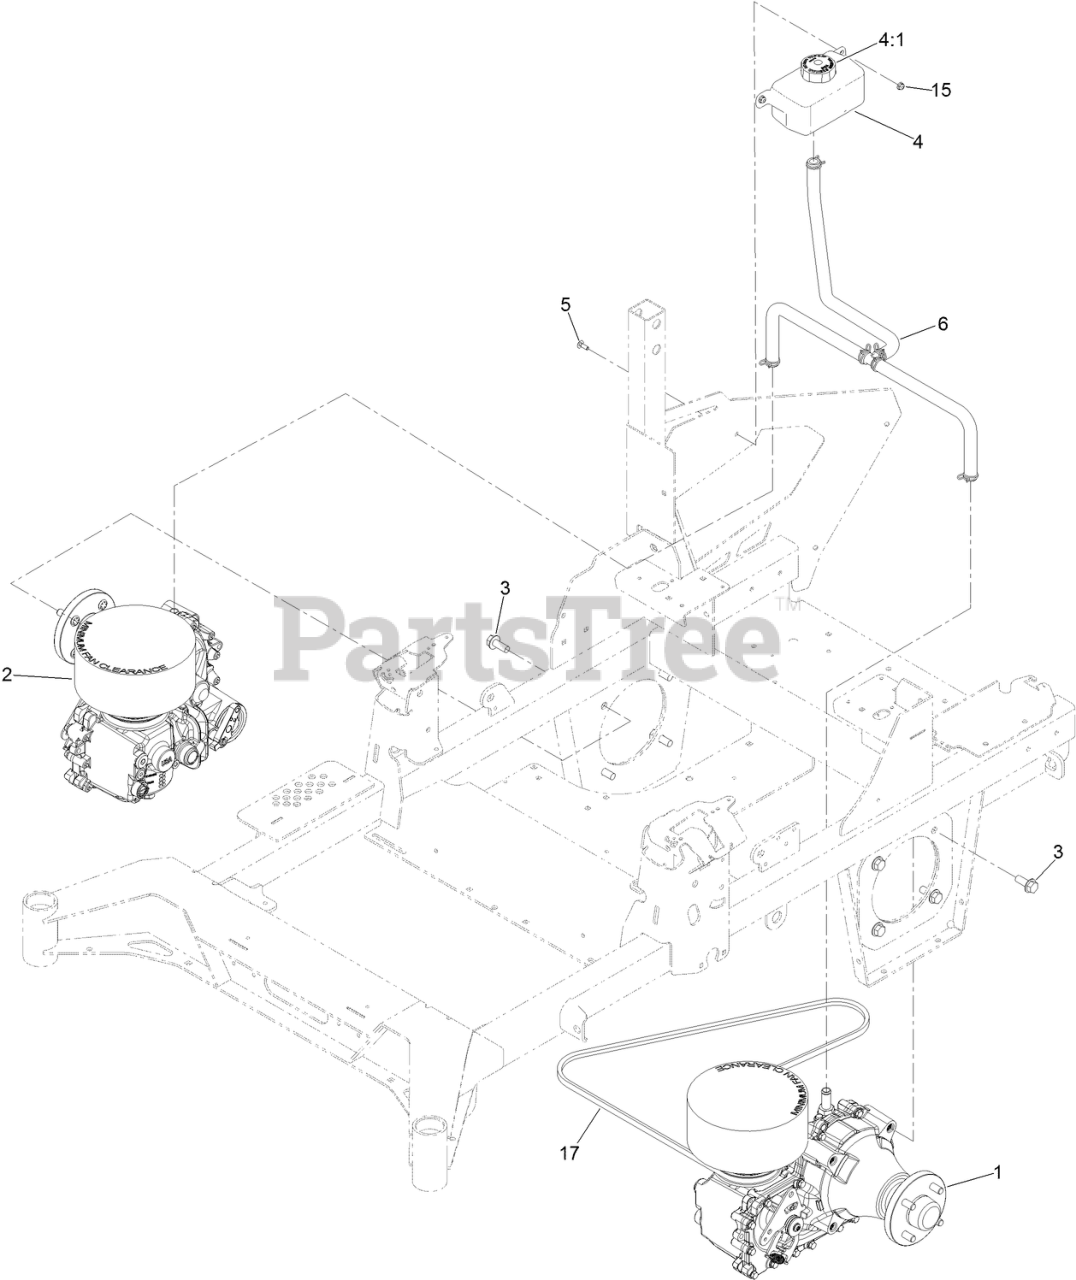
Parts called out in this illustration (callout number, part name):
1	LH TRANSAXLE ASM
2	RH TRANSAXLE ASM
3	SCREW-HHF
4	HYDRAULIC RESERVOIR ASM
4:1	CAP-RESERVOIR, HYD
5	SCREW-CARR
6	ASM-HOSE, HYDRAULIC
15	NUT-HF
17	BELT-V
